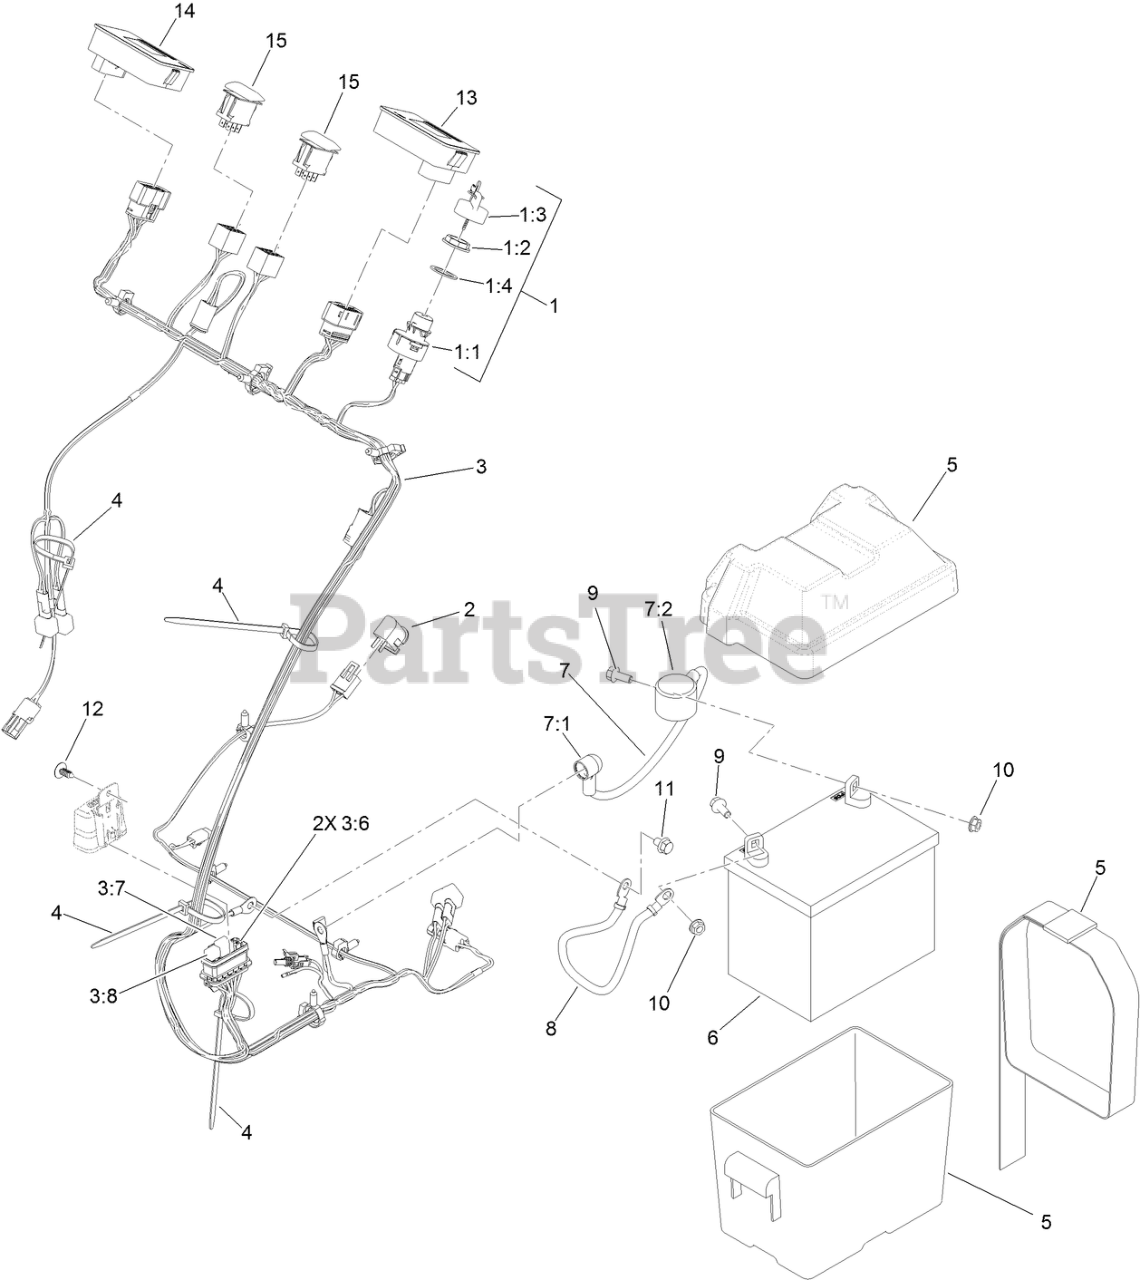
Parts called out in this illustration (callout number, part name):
1	IGNITION SWITCH ASM
1:1	SWITCH-IGNITION
1:2	NUT-MOUNTING
1:3	IGNITION KEY SET
1:4	WASHER-BACKUP
2	SWITCH-BAIL
3	HARNESS-WIRE
3:6	FUSE-MINI BLADE, 20 AMP
3:7	RELAY-MICRO
3:8	RELAY-COIL, NC, MP280
4	TIE-PLASTIC
5	BATTERY BOX
6	BATTERY
7	POSITIVE BATTERY CABLE ASM
7:1	INSULATOR-SOLENOID
7:2	INSULATOR-BATTERY
8	CABLE-BATTERY, NEGATIVE
9	SCREW-HHF
10	NUT-HF
11	SCREW-HHF
12	PLUG-PLASTIC
13	HOUR METER ASM
14	HOUR METER ASM
15	SWITCH
